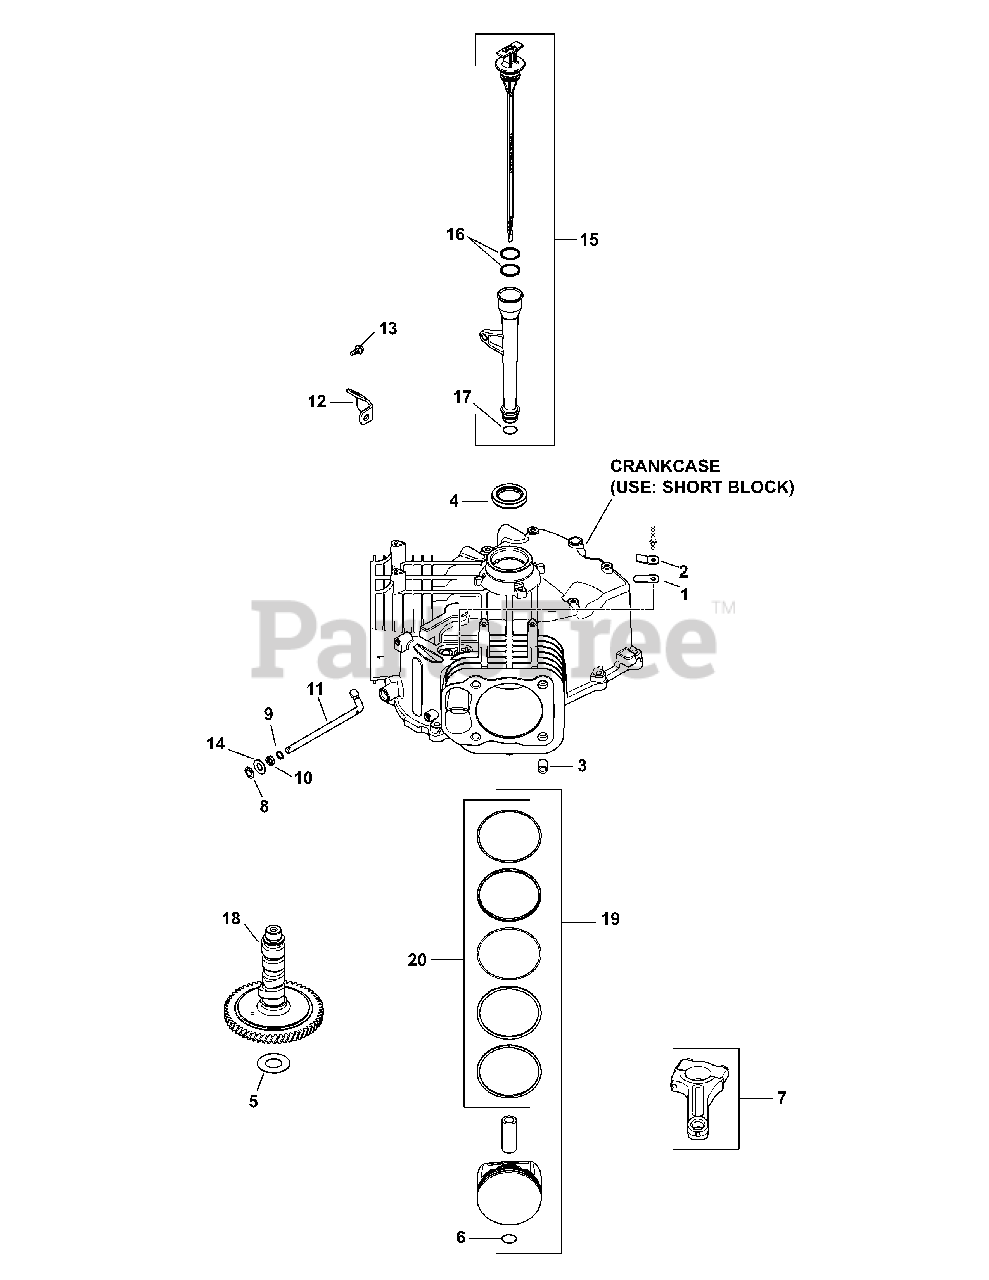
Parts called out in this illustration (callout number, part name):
1	Breather Reed
2	Breather Reed Retainer
4	Oil Seal (Helix Lip)
5	Camshaft Shim (White .028")
5	Camshaft Shim (Blue .03")
5	Camshaft Shim (Red .032")
5	Camshaft Shim (Yellow .034")
5	Camshaft Shim (Green .036")
5	Camshaft Shim (Gray .038")
5	Camshaft Shim (Black .04")
6	Piston Pin Retainer
7	Connecting Rod (Std)
8	Ring Retainer
9	Flat Washer, 11/32
10	Governor Cross Shaft Seal
11	Governor Cross Shaft
12	Oil Fill Tube Bracket
13	Flg. Thd. Frm. Screw, M5 x 0.8 x 13
14	Flat Washer, 9mm
15	Dipstick & Tube Kit
16	Dipstick O-Ring
17	O-Ring, Lower Oil Fill Tube
18	Camshaft Assembly
19	Piston Kit w/ Ring
19	Piston Kit w/ Ring (0.25) 83mm
19	Piston Kit w/ Ring (0.08) 83mm
20	Ring Set, Piston STD
20	Ring Set, Piston (.08)
20	Ring Set, Piston (.25)
